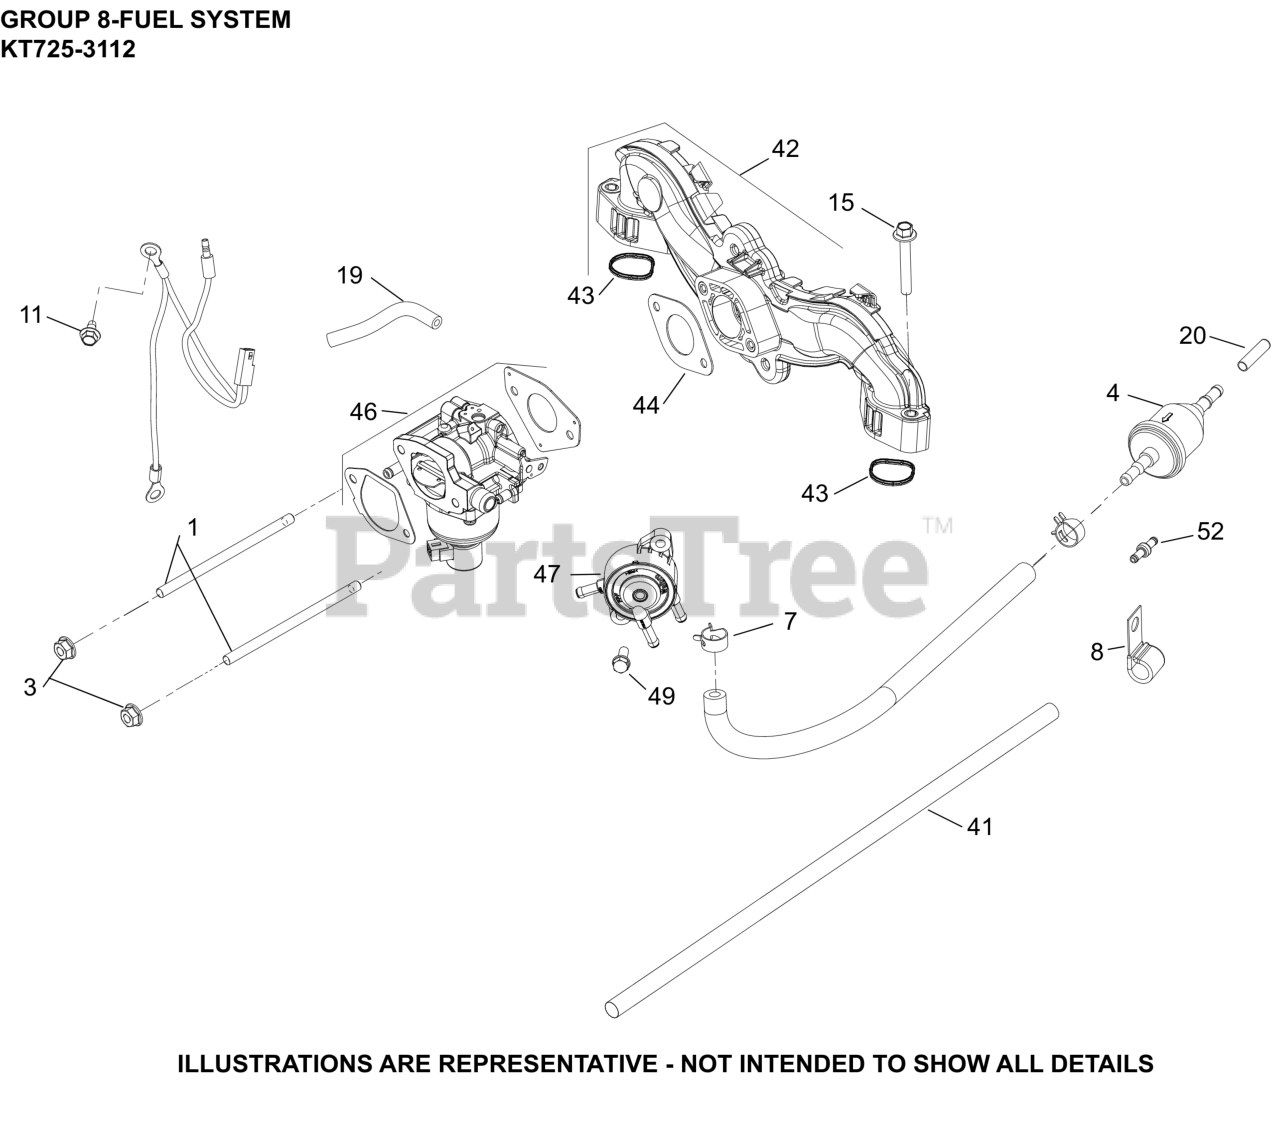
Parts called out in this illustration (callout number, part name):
3	NUT, FLG M6X1.0
4	FILTER,FUEL 51 MICRON (FUEL PUMP)
7	SPRING CLAMP, HOSE
8	CLIP, CABLE (KM)
11	SCREW, THREAD FORMING
15	SCREW, FLG M6X1.0X40
19	HOSE, EVAPORATIVE 20"- (#24326143S)
20	CAP, MASKING
41	SLEEVE, ANTI-ABRASION
42	INTAKE MANIFOLD W/GASKETS
43	O-RING, INTAKE PORT
44	GASKET, CARBURETOR (PIM, CV)
46	KIT,CARB(NIKKI)
47	PUMP, FUEL (PULSE)
49	SCREW, HEX HEAD
52	FITTING, FUEL SYSTEM
NI	KIT, BOWL WITH O-RINGS NIKKI G-TYPE TWIN
NI	KIT, FLOAT AND NEEDLE NIKKI G-TYPE TWIN
NI	KIT,CHOKEREPAIR NIKKI G-TYPE T-DISC.
NI	KIT, O-RING (NIKKI)
NI	KIT, SOLENOID (NIKKI)
NI	KIT, HIGH ALT (NIKKI)(4000-8000 FT)
